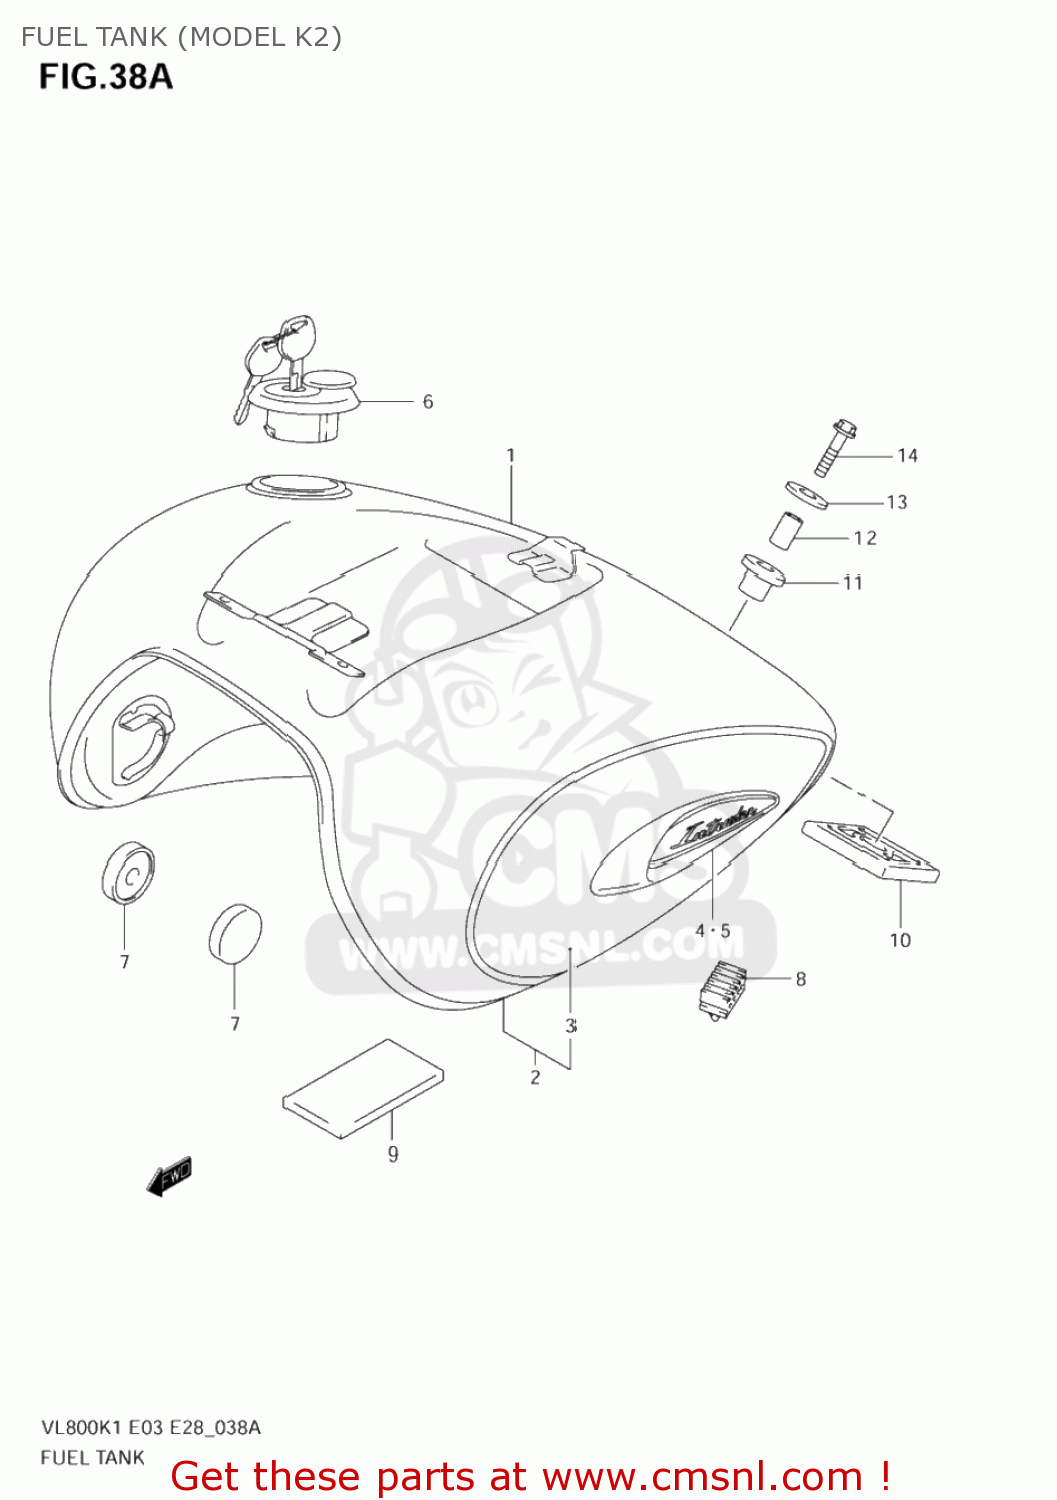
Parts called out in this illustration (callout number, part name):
1	TANK ASSY,FUEL(BLACK)
2	TANK ASSY,FUEL
3	TAPESET,FUEL T
4	EMBLEM,FUEL TANK,R
5	EMBLEM,FUEL TANK,L
6	CAP SET,FUEL TANK
7	CUSHION
8	CUSHION,SEAT(40X20X15)
9	CUSHION,FUEL TANK
10	CUSHION,FUEL TANK RR LWR
11	CUSHION,FUEL T
12	SPACER (8.2X12.5X23.5)
13	WASHER (8.5X33X1.6)
14	BOLT
